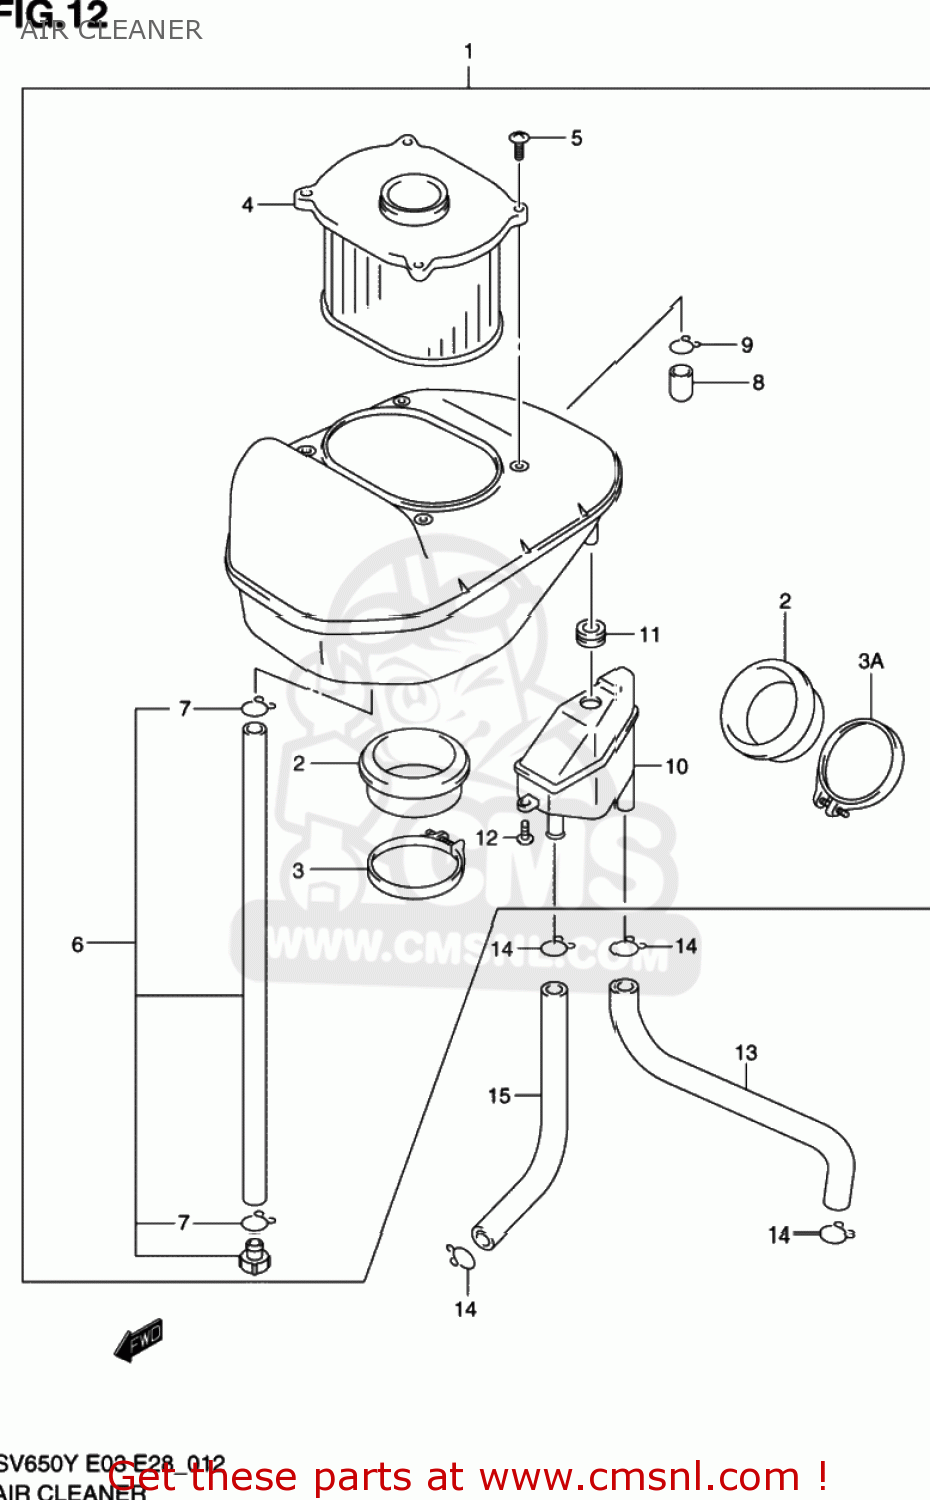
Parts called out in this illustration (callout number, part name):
1	CLEANER ASSEMBLY,AIR
2	TUBE,OUTLET
3	CLAMP,OUTLET TUBE FR
3A	CLAMP
4	FILTER,AIR CLEANER
5	SCREW 5X20
6	TUBE,DRAIN
7	CLIP
8	PLUG
9	CLIP
10	TANK,OIL RETURN
11	GROMMET
12	SCREW
13	TUBE,BREATHER CRANKCASE
14	CLIP
15	HOSE(11X16X600)
